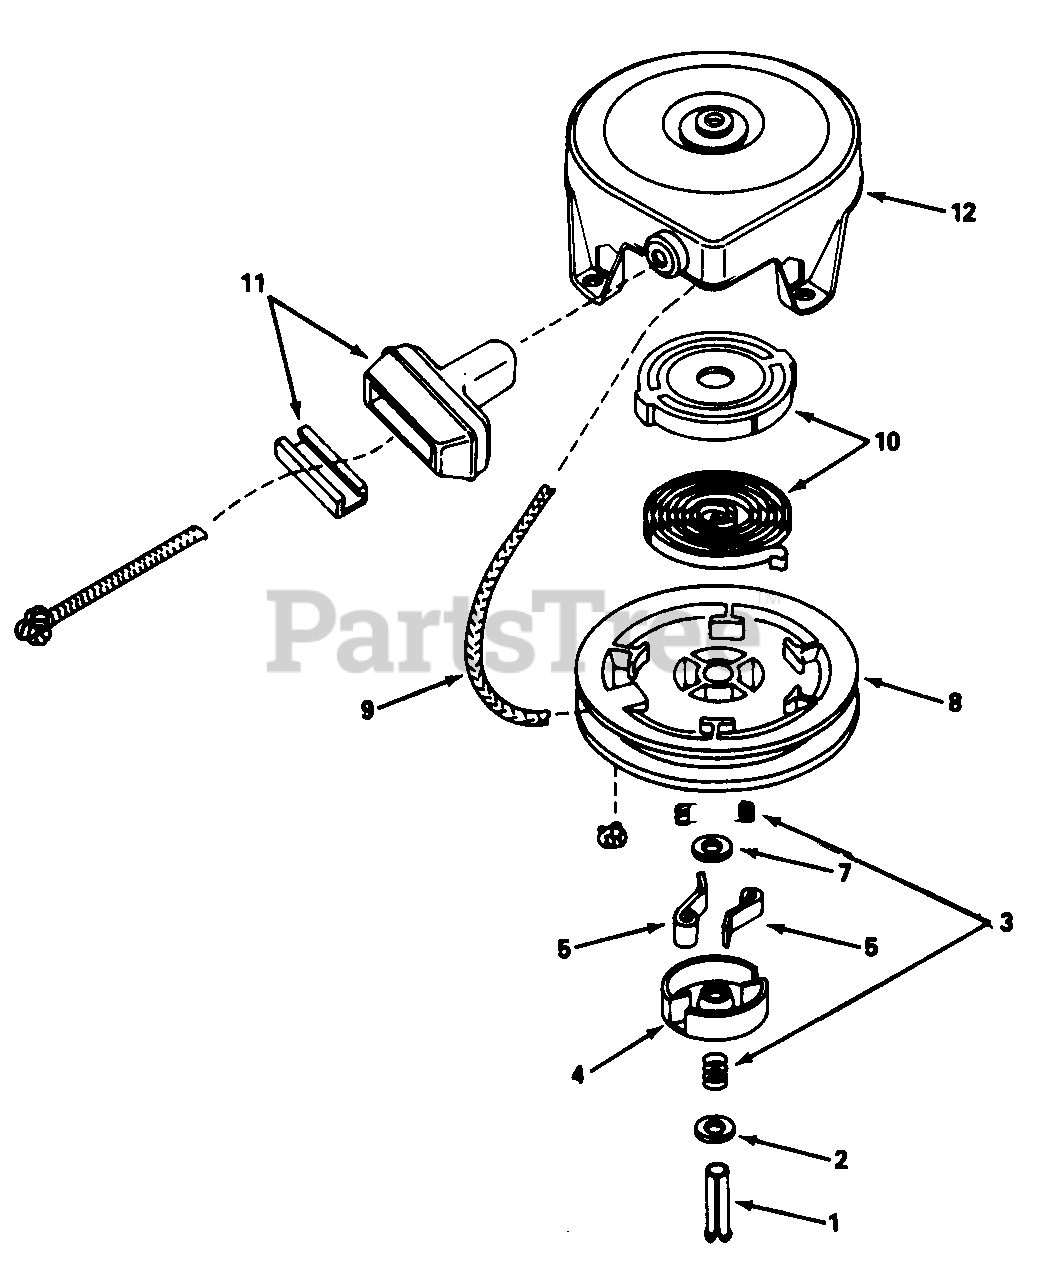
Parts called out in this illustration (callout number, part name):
1	Pin, Spring
3	Spring Ass'y., Brake & Dog
5	Dog, Starter
9	Rope, Starter
10	Spring & Keeper Ass'y.
11	Handle Ass'y., Starter
12	Housing Ass'y., Starter
